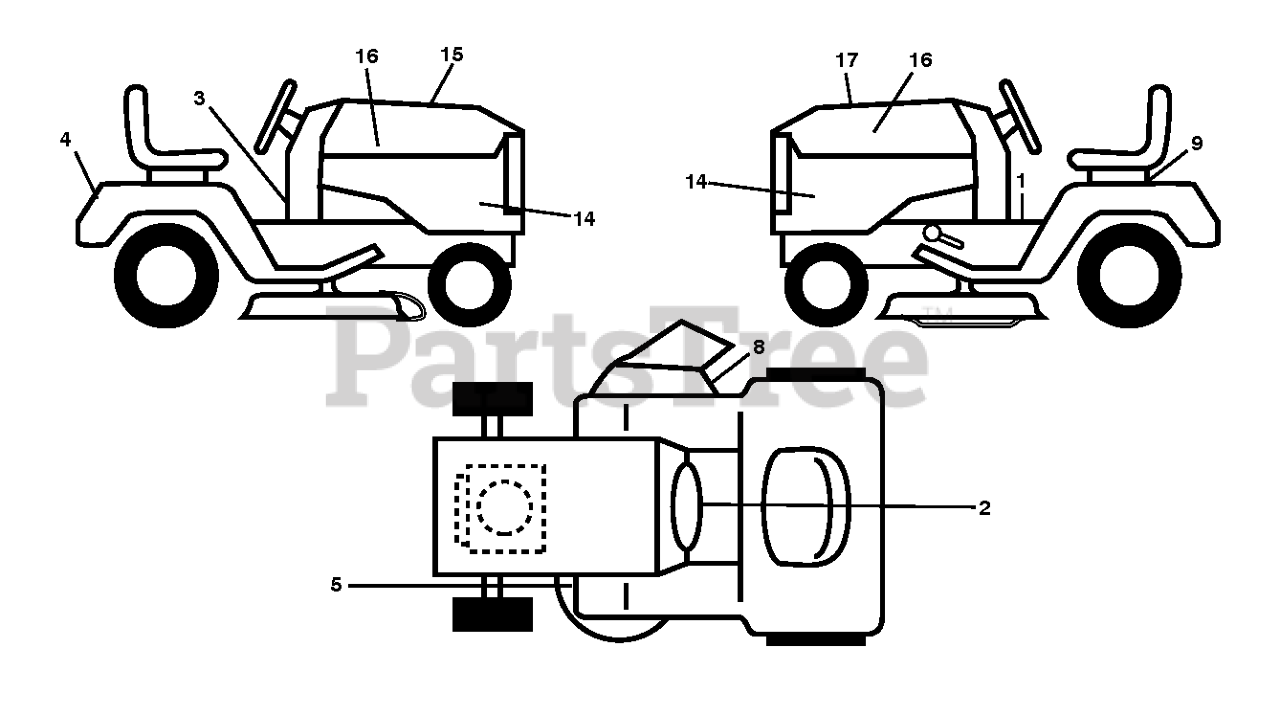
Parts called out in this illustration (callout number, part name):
1	DECAL.WARN.START.INSTRUCTIONS
2	LABEL.EMISS.CA.HUSQ/LOWES.2011
3	DECAL, WARNING SPARK ARRESTOR
4	DECAL.FENDER
5	DECAL.MOWER
8	DECAL.MOWER.SCH.48/54
9	DECAL BTRY SYMBOLS
14	DECAL.PNL.SD.LGT2554.KOHL.
15	DECAL.WARNING.CUST.RESP.E85.
16	RP.DECAL.BADGE.170MM.TEXTLOGO
